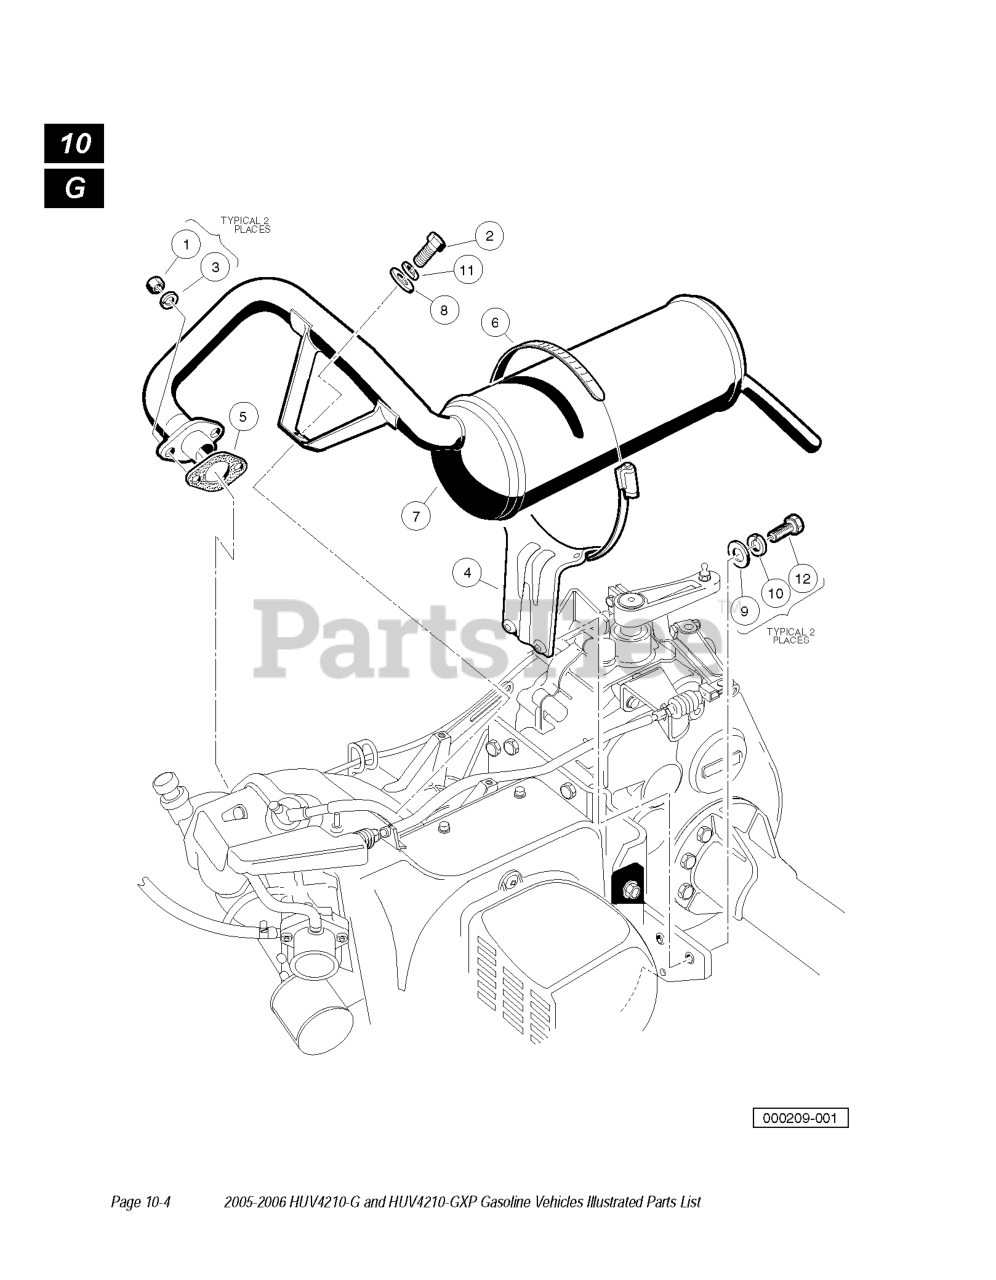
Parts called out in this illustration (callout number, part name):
1	NUT, M8-1.25 HEX
2	SCREW, M8-125 X 22 HEX GR.8.8
4	BRACKET, MUFFLER MOUNTING
5	GASKET, FE350 EXHAUST
6	CLAMP, 5" MUFFLER HOSE
7	EXHAUST SYSTEM, FE350
8	WASHER, 5/16 TYPE A FLAT
9	WASHER 1/4 FLAT
10	LOCKWASHER, 1/4 HELICAL SPLIT
11	LOCKWASHER, 5/16 SPLIT
12	SCREW, 1/4-20 X .75 HEX
